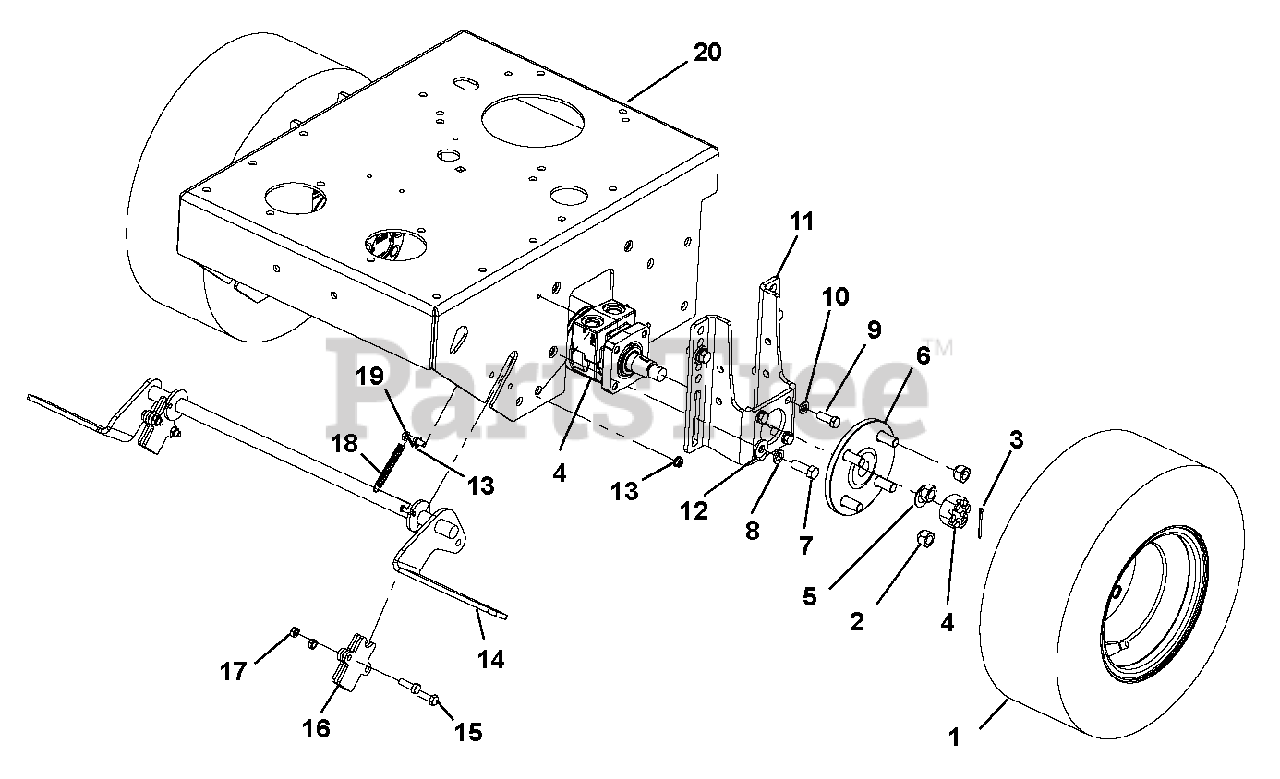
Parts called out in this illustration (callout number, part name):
1	Assembly, Wheel and Tire- 16 x 6.5-8
2	Nut, .50-20 Lug
3	Pin, Cotter .125 x 1.50 ExTP
4	Motor, Hydraulic Wheel
5	Bushing, Machine .750 x 1.25 x .048
6	Assembly, Wheel Hub
7	Bolt, .44-14 x 1.25 Hex Grade 5
8	Washer, .438 Medium Spring Lock
9	Bolt, .38-16 x 1 Grade 8 Black
10	Washer, .375 Medium Spring Lock
11	Bracket, Motor Mount (988400)
12	Washer, .468 x 1.00 x .125 Flat
13	Locknut, .25-25 WHIZ
14	Weldment, Brake System (988400)
15	Bolt, .31-18 x 1 Hex Grade 5
16	Shoe, Brake System Float Walk
17	Locknut, .3125-18 Nyloc
18	Spring, Ext .375 x .055 x 2.25
19	Bolt, .25-20 x 1.25 Grade 5
20	Weldment, 18" Engine Bed FXFLWasp
